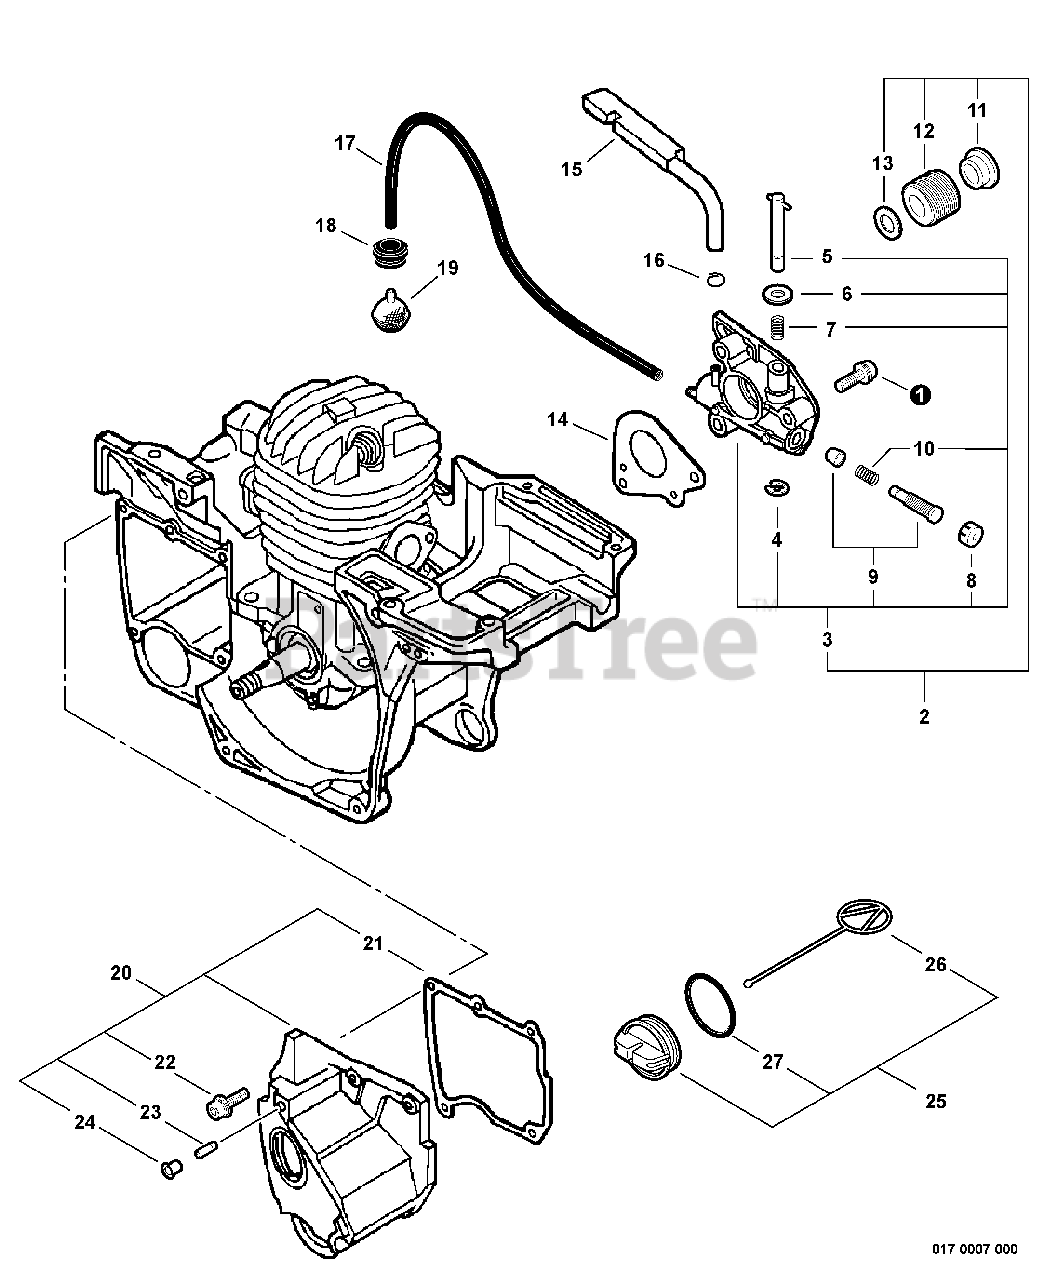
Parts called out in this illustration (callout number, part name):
1	SCREW 4×16
2	AUTO-OILER ASSY
3	AUTO-OILER ASSY
5	SCREW, ADJUSTER
8	CAP, OIL PUMP
9	PLUNGER ASSY
11	COLLAR 10
12	GEAR, WORM
13	WASHER 10.5×17.4×1.8
14	PLATE, SEAL
15	PIPE, OIL OUTLET
16	CLIP Ø6.5 MM
17	PIPE, OIL
19	FILTER, OIL
20	TANK ASSY, OIL
21	GASKET, OIL TANK
22	BOLT 4×16
23	VENT ASSY
24	COLLAR 5.5×6.65×5
25	CAP ASSY
26	CONNECTOR, CAP L= 60 MM
27	O-RING 25
